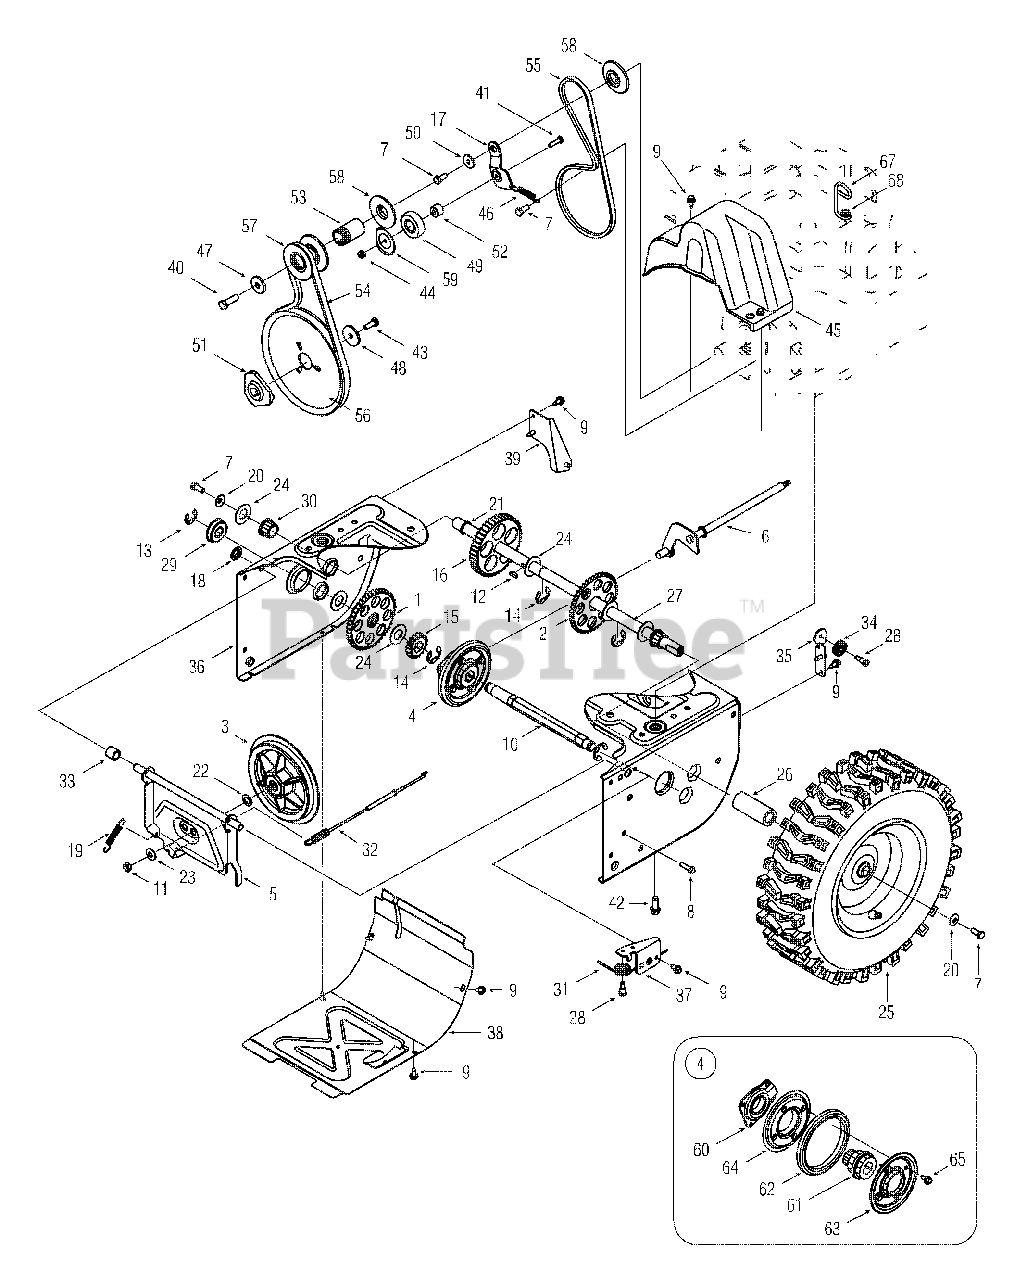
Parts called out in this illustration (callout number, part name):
1	Gear Assembly, 16/44T
2	Gear Assembly, 16/44T
3	Disc Assembly, Friction Wheel,.375
4	Wheel Assembly, Friction, 4.9 OD
7	Screw, 5/16-24 x.750, Gr5
8	Screw, 1/4-20 x 1.000
9	Screw, 1/4-20 x.625
10	Hex Shaft, Drive,.75
11	Nut, Jam, 3/8-24, Gr2
12	Key, Hi-pro 3/16 x 5/8
13	Ring, E Type,.750
14	Ring, E-Type,.875
15	Pinion, 16T
16	Gear, 44T
19	Extension Spring
20	Washer, Bell,.340 x.872 x.060
21	Washer, Flat,.75 x 1.00 x.060
22	Washer, Flat,.406 x.875 x.059
23	Washer, Bell,.375 x.870 x.063
24	Washer, Flat,.793 x 1.24 x.060
25	Wheel Assembly Complete, 13 x 4
25	Wheel Assembly Complete, 15 x 5
26	Spacer, 1.25 OD x.75 ID x 3.00
27	Axle,.75 x 22
28	Screw, 1/4-28 x.375
29	Bearing, Ball, 17 x 40 x 12
30	Bearing, Hex Flange x.75 ID
31	Cable, Auger, 44.75
32	Cable, Drive, 41.75
33	Spacer,.508 ID x.75 OD x.68
34	Roller, Cable
41	Screw, 1/4-20 x 1.00, Gr5
42	Screw, Sems, 3/8-16 x 1.00
43	Screw, 5/16-24 x.875, Gr8
44	Nut, Flange Lock, Nylon, 1/4-20, Gr F
45	Cover, Belt
46	Spring, Extension,.38 OD x 2.68
47	Washer, Flat,.406 x 1.25 x.157
48	Washer, Flat,.34 x 1.50 x.150
49	Bearing, Ball, 20 x 47 x 14
50	Shoulder Spacer
51	Pulley, Adapter,.75 Dia.
52	Spacer,.777 OD x.260 ID x.550
53	Spacer,.875 ID x 1.185 OD
54	V-Belt, 1/2"
55	V-Belt, 3/8"
56	Pulley, Auger, 8.1 x.50
57	Pulley, Half, 2.600 OD
58	Pulley, Half, 2.2 OD
59	Washer, Bearing, 2.12 OD x.255 ID
60	Bearing Assembly, Friction Wheel
61	Hub, Friction Wheel
62	Friction Wheel Rubber, 4.875 OD
63	Plate, Friction, 12 Pt 4.60 Dia
64	Plate, Friction, Extrs, 12 Pt 4.60 Dia
65	Screw, Self-tapping, 1/4-14 x 0.625
67	Chute Cable Guide
68	Screw, 5/16-18 x 1.00
